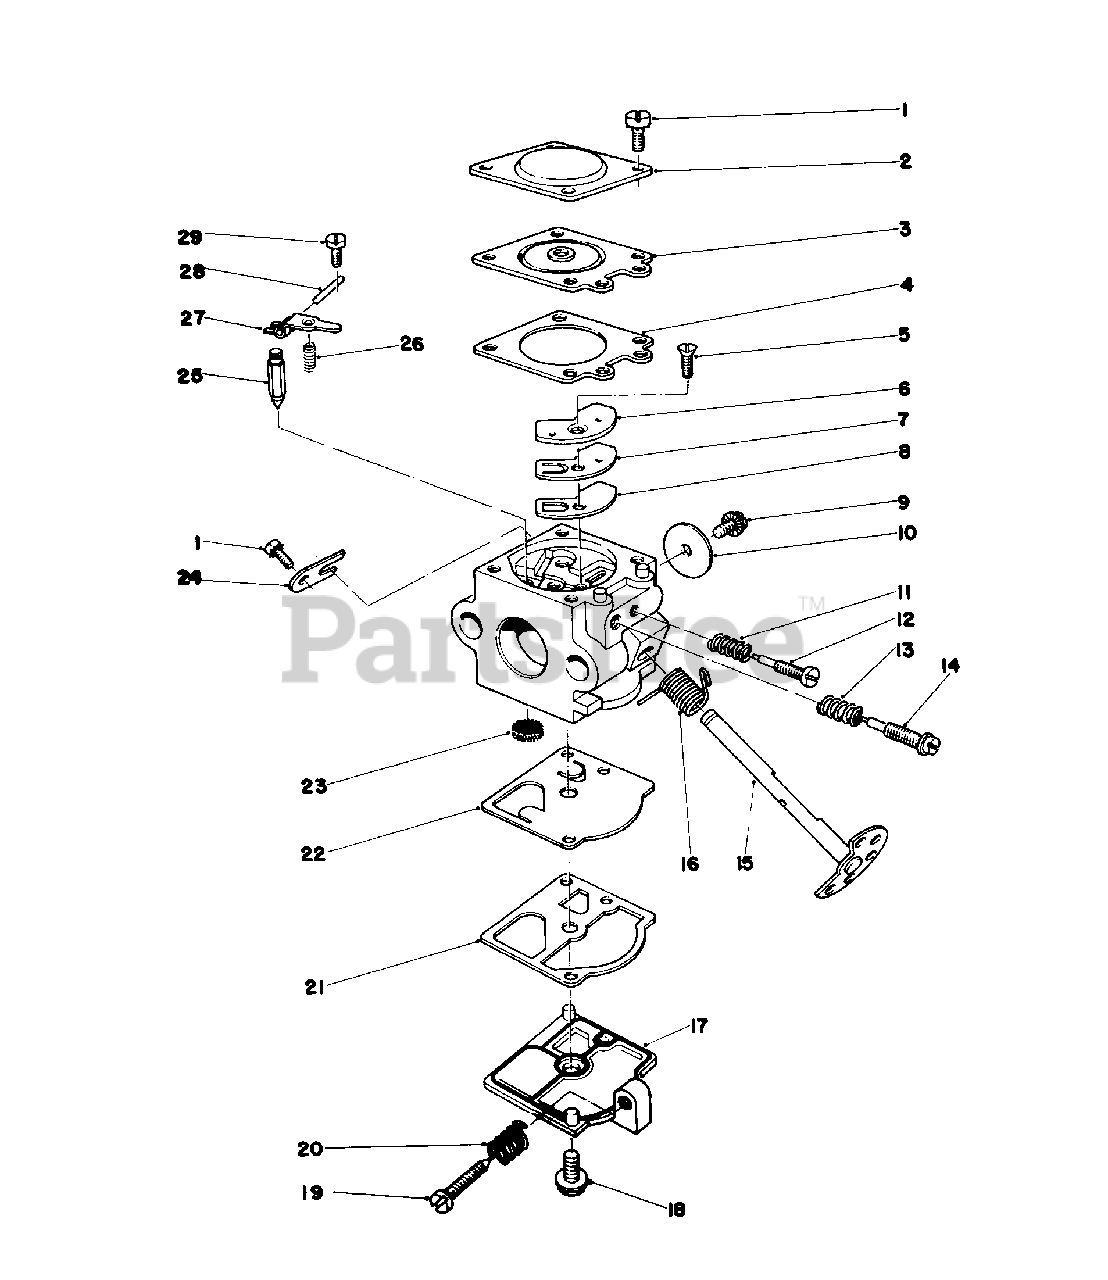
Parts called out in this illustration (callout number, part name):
2	Cover, Metering Diaphragm
3	Diaphragm, Metering
4	Gasket, Metering Diaphragm
5	Screw, Circuit Plate
6	Plate, Circuit
7	Diaphragm, Circuit Plate
8	Gasket, Circuit Plate
10	Valve Throttle
11	Spring, Idle Needle
12	Needle, Idle
13	Spring High Speed Needle
14	Needle, High Speed
15	Shaft, Throttle
16	Spring, Throttle Return
17	Cover, Fuel Pump
19	Screw, Idle Adjustment
20	Spring, Idle Screw
21	Gasket, Fuel Pump
22	Diaphragm, Fuel Pump
23	Screen, Inlet
24	Clip, Throttle Shaft
25	Valve, Inlet Needle
26	Spring, Metering Lever
27	Lever, Metering
28	Pin, Metering Lever
29	Screw, Metering Lever
